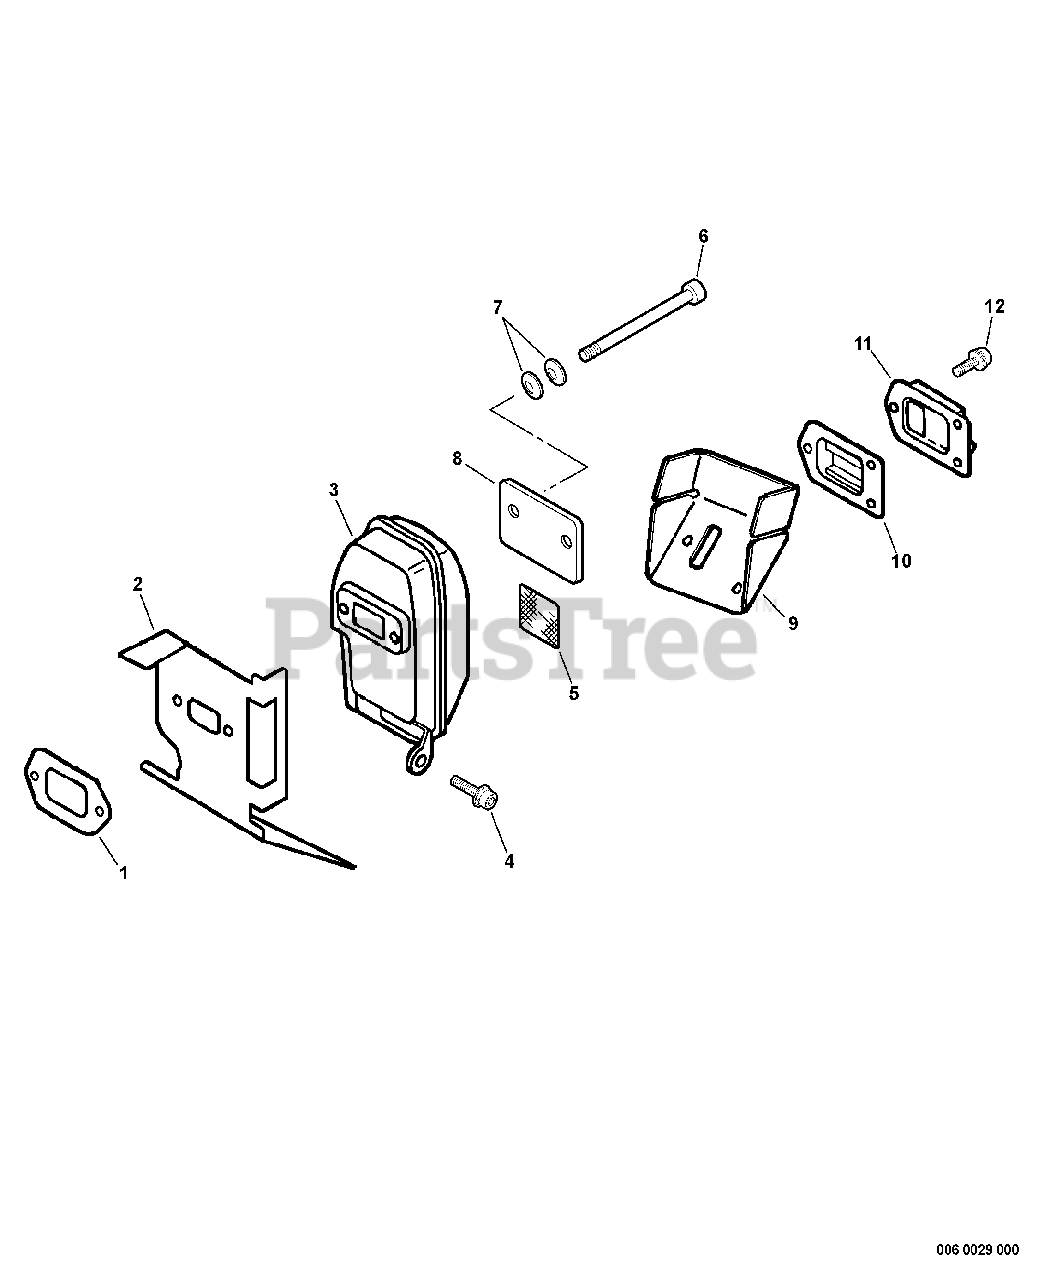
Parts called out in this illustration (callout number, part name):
1	GASKET, EXHAUST
2	HEAT SHIELD, EXHAUST
3	MUFFLER
4	BOLT 5×16
5	SCREEN, SPARK ARRESTER
6	BOLT M5×65
7	CONICAL WASHER
8	PLATE, EYE
9	GASKET, EXHAUST
10	GUIDE, EXHAUST
11	GUIDE, EXHAUST
12	SCREW 4×12
